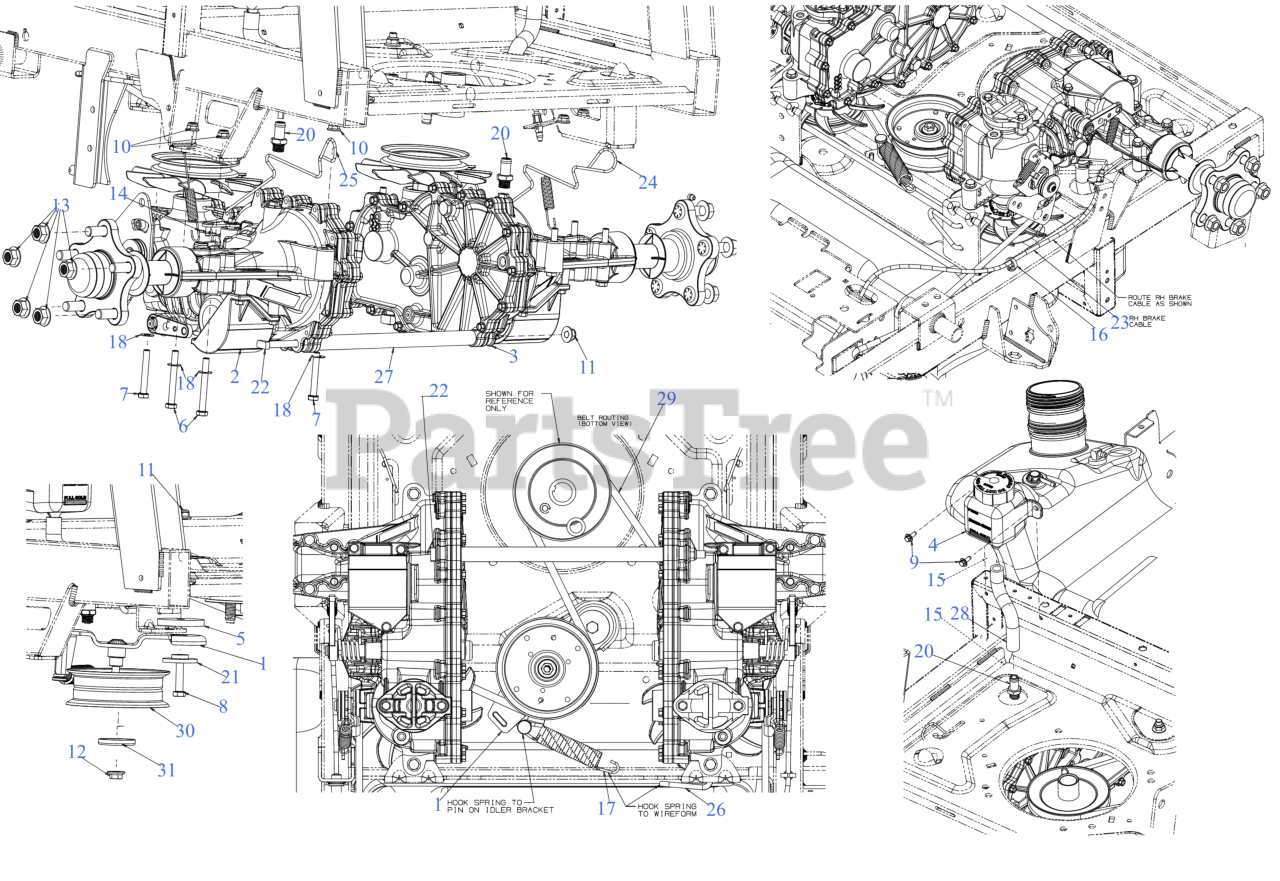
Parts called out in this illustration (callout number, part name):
1	DRIVE IDLER BRACKET
2	HYDRO TRANSMISSION (LH)
3	HYDRO TRANSMISSION (RH)
4	EXPANSION TANK
4	CAP-EXPANSION TANK
5	SPACER PLATE
6	HEX SCREW 5/16-18 x 2.75
7	HEX SCREW 5/16-18 x 2.25 GR5
8	SCREW 3/8-16 x 1.50
9	SCREW M6-1 x .625
10	FLANGE LOCK NUT 5/16-18
12	FLANGE LOCK NUT
13	HEX FLANGE NUT 1/2-20 GR8
14	BOW TIE COTTER PIN 1/4-5/16
15	FUEL HOSE CLAMP .75
16	CABLE RETAINER CLIP
17	EXTENSION SPRING .925 x 5.37
18	FLAT WASHER
20	BARB FITTING 9/16-18
21	SHOULDER SPACER
22	SUPPORT TUBE ROD
23	PARK BRAKE CABLE
24	HYDRO BYPASS ROD (RH)
25	HYDRO BYPASS ROD (LH)
26	IDLER SPRING HOOK
27	SUPPORT TUBE
28	EXPANSION TANK HOSE
29	TRANSMISSION DRIVE BELT A x 67
30	IDLER PULLEY 4.50" DIA
31	IDLER PULLEY CAP
